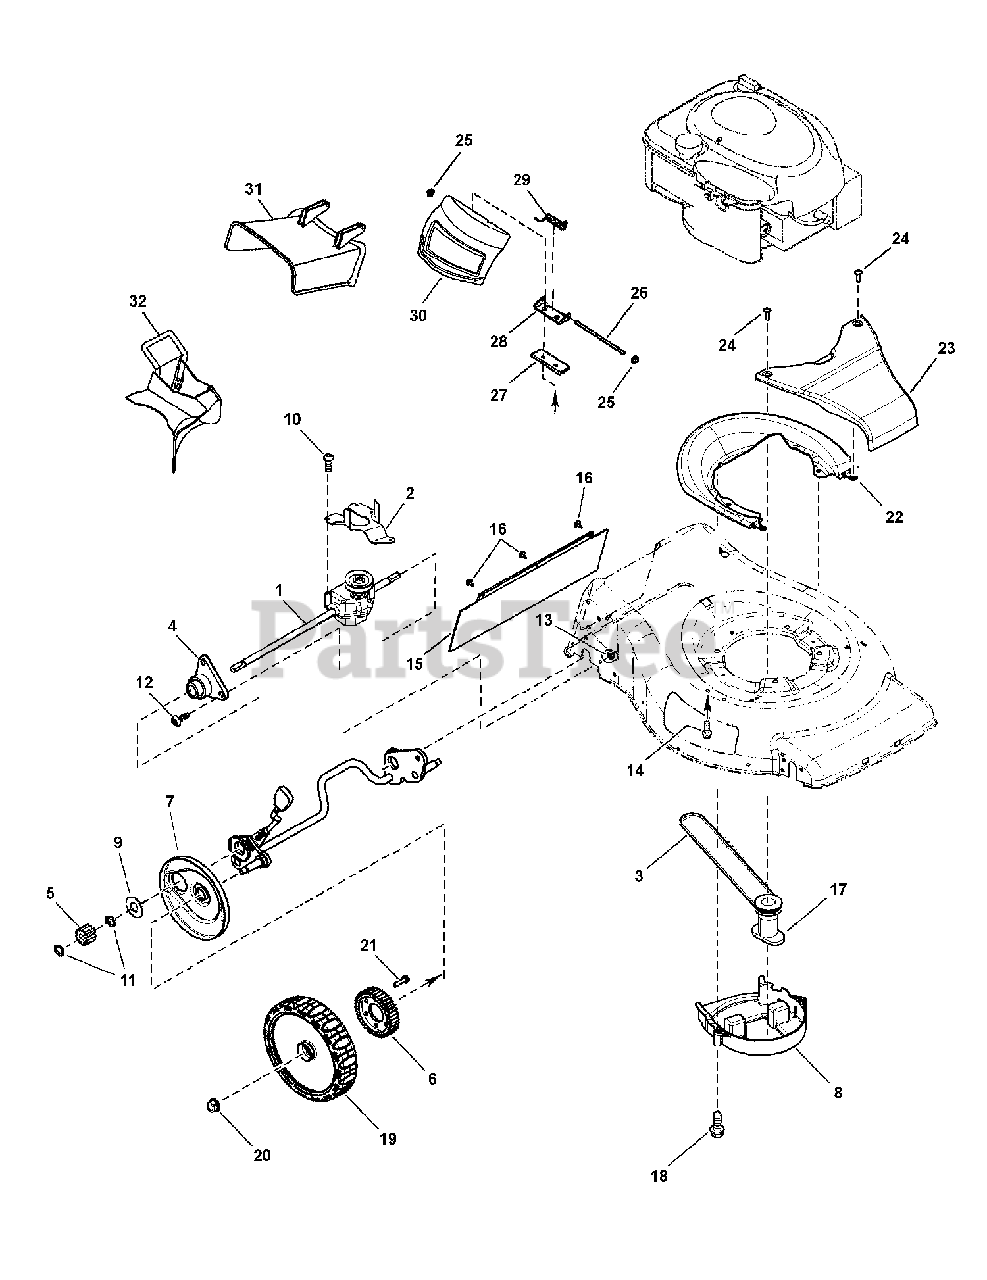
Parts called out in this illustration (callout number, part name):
1	TRANSMISSION, Self-Propel
2	BELT GUIDE, Transmission
3	BELT, Drive, 3L 32.5" EL
4	RETAINER ASSEMBLY, Ball Bearing (Includes: 880786 Retainer, 880788 Bearing)
5	GEAR, Pinion 11 Tooth, .91" Lg, .503 Oblong ID
6	GEAR, Wheel, 39T
7	COVER, Dust, RH
8	BELT GUIDE, Front
9	WASHER, Thrust, .506" ID, 1.177" OD
10	SCREW, #10-14 x .88 Plastite
11	RING, .46" ID, .050" Thk, Retaining
12	SCREW, 1/4-20 X 5/8, Torx Truss Head
13	NUT, Flange Lock, 1/4-20, BZ
14	SCREW, 1/4"-20 X 1/2" Taptite Pan Head
15	GUARD, REAR
16	SCREW, Self-Tapping Washer Head, #10-16 x .5
17	ADAPTER, Blade, Self-Propelled
18	SCREW, 3/8-16 X 1.0, Hex Washer Self-Tap, ZC/CL
19	WHEEL ASSEMBLY, Rear, Self-Propelled, 200MM (7.1"), BBSP TREAD III
20	NUT, Flange Lock 3/8-16
21	SCREW, Hex Head, 1/4 x 1" Hi-Lo Thread
22	COVER, Rear, 19, SD
23	COVER, Front, 19, SD
24	SCREW, 1/4-20X7/8, Torx Truss Head
25	NUT, 1/4", Push, Zinc/Clear
26	ROD, Mulch Cover
27	SPACER, Mulch Cover Bracket
28	BRACKET, Mulch Cover
29	SPRING, Mulch Cover Torsion
30	COVER, Mulch, Black
31	DEFLECTOR, Chute, Black
32	PLUG, Mulch
